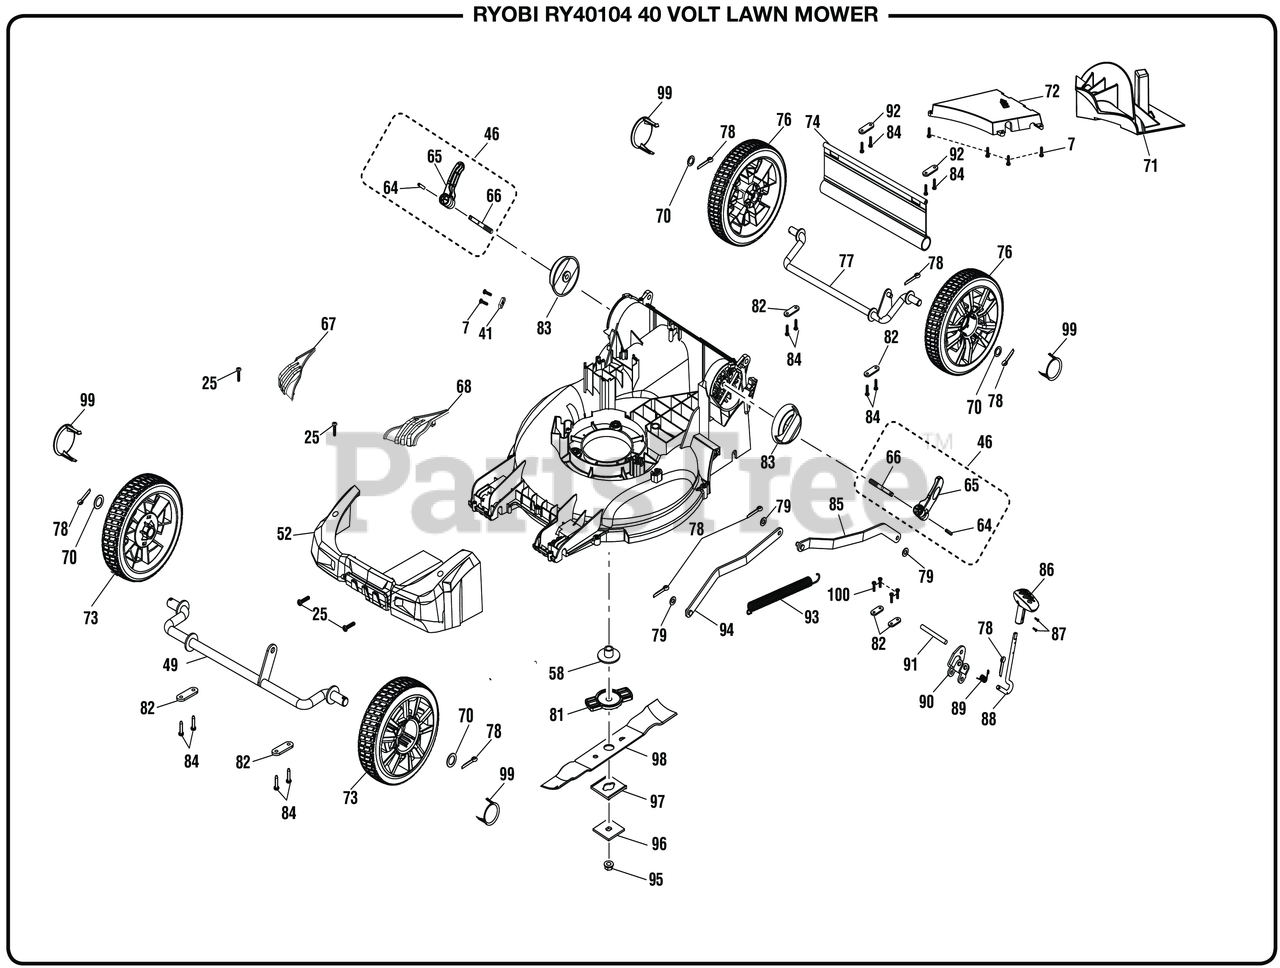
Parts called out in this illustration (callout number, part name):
7	Screw (M4 x 16 mm, T20 Torx Pan Hd.).
25	Screw (M4 x 20 mm, T20 Torx Pan Hd. S.T.)
41	Wire Press Plate
46	Handle Lock Assembly
49	Front Wheel Axle
58	Motor Shaft Bushing
64	Spring Pin
65	Adjust Height Handle
66	Quick Lock Press
67	Grass Protector (Right)
68	Grass Protector (Left)
70	Washer (ID13.5 x OD20 x 1t)
71	Mulching Plug
72	Rear Cover
73	Front Wheel w/Bearing & Cap 6 in.
74	Rear Skirt
76	Rear Wheel w/Bearing & Cap 8 in.
77	Rear Wheel Axle
78	Cotter PinÏ? (2.5)
79	Washer (ID8.4 x OD18 x 1t)
81	Blade Holder
82	Axle Pressure Plate
83	Quick Lock Press Block
84	Screw (M4 x 18 mm, T20 Torx Pan Hd.)
85	Rear Lift Rod
86	Height Adjustment Handle
87	Screw (M3 x 9 mm, Flat Hd.)
88	Height Adjustment Lever
89	Torsion Spring (Height Adjustment)
90	Adjustment Height Bracket
91	Axle (Height Adjustment)
92	Pressure Plate (Height Adjustment)
93	Rentention Spring
94	Front Lift Rod
95	Blade Nut (M10 x 1.25, Hex Flange Hd.)
96	Metal Blade Retainer
98	Blade (16 in.)
99	Wheel Cover (Before Serial Number EU18234D020307)
100	ST SCREW,STEEL CH M4.0X1.8 PH TORX
